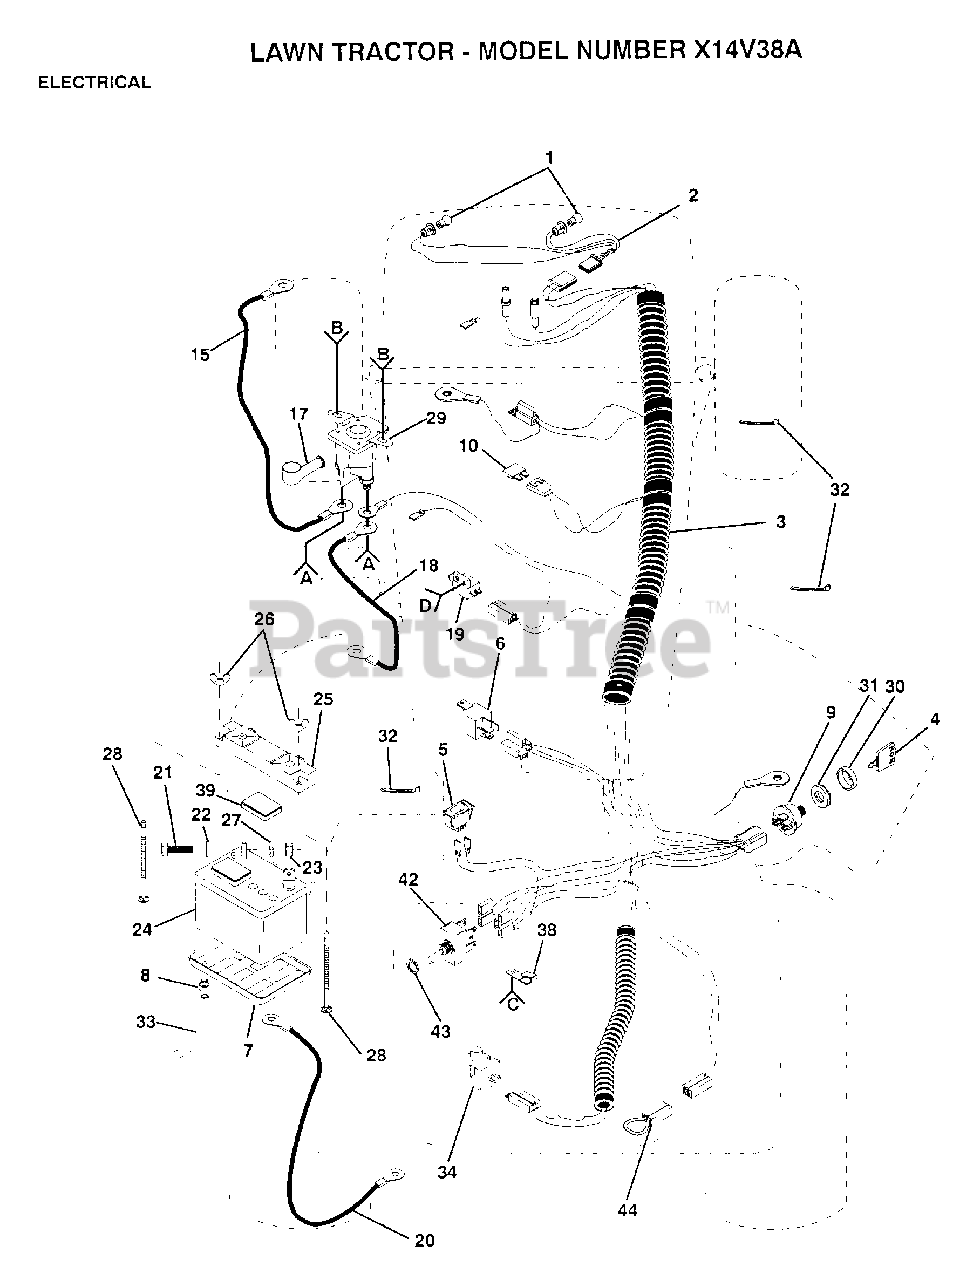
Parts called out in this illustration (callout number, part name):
2	HARNESS T
3	IGNITION HARNESS
4	KEY
5	SWITCH LT
6	RELAY ASSY T
7	"TRAY T, BATTERY"
8	HOSE CLAMP T
10	FUSE HYT
15	"CABLE T, BATTERY"
18	STARTER CABLE GT
19	SWITCH-INTER. GT
20	CABLE T
21	BOLT LT
22	WASHER
27	LOCKWASHER
28	BOLT
32	WIRE TIE
34	SWITCH SEAT
39	"CAP,BATTERY "
43	HEX NUT T
